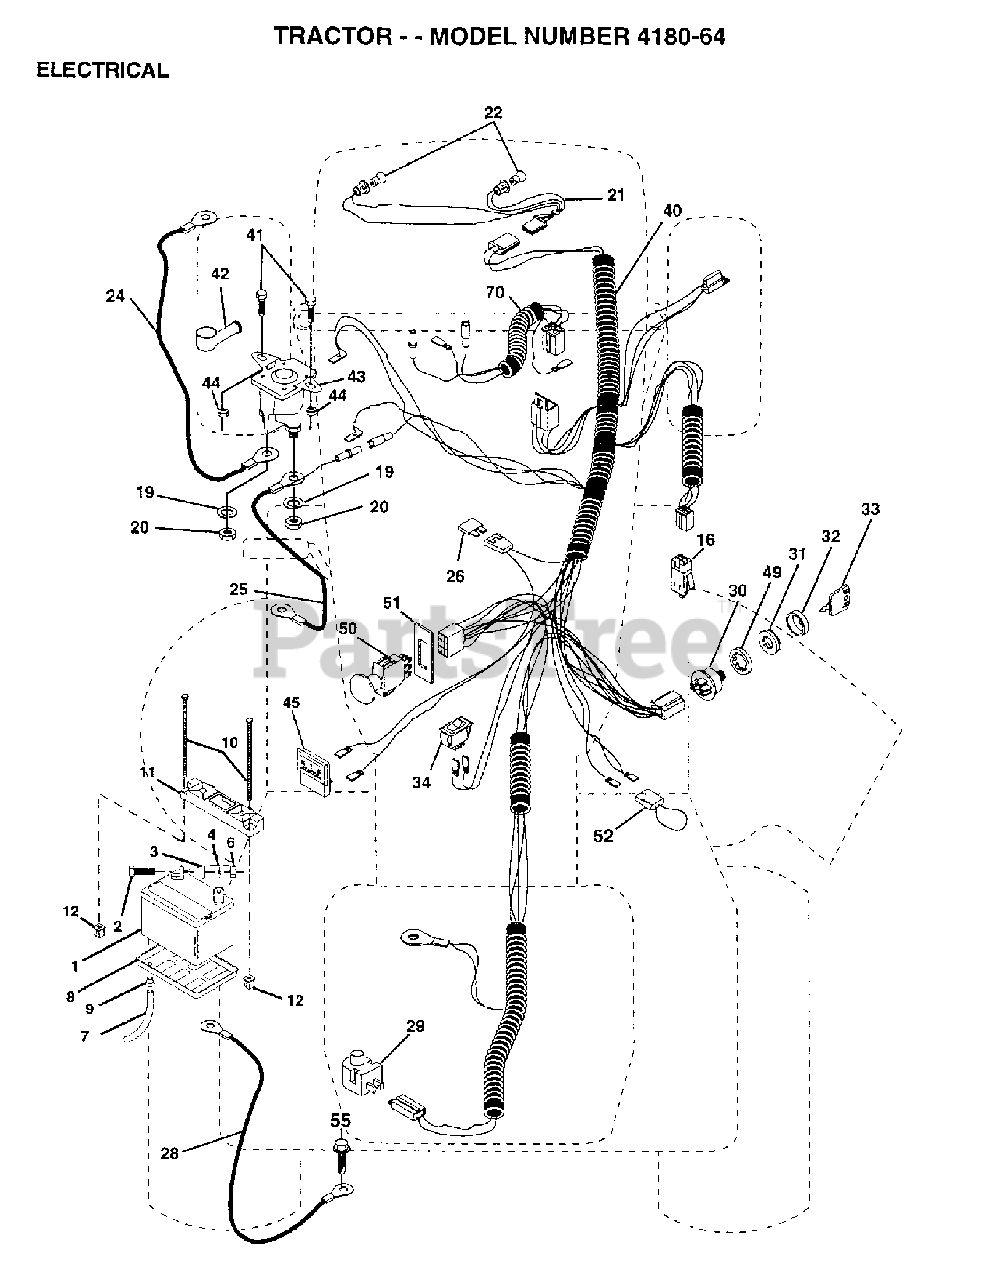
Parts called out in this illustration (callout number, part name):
1	BATTERY 12 VOLT 30 AMP WET
2	BOLT.HEX.1/4.X.3/4.DICHROMATE
3	WASHER
4	LOCKWASHER
5	NUT
7	BATT DRAIN TUBE T
8	TRAY.BATTERY
9	HOSE CLAMP T
10	BOLT 1/4-20 X 7.5
20	NUT
22	LIGHTBULB
24	BATTERY CABLE
25	CABLE BATTERY 6 GA 22" W/16W
26	FUSE *
28	CABLE GROUND 6 GA 21" 90T BLK
29	SWITCH SEAT
30	Ignition Switch Kit
31	NUT, IGNITION
32	COVER KEY IGNITIO
33	KEY MLD GEN DELTA
34	SWITCH LT
41	BOLT
42	TERMINAL COVER
43	Solenoid Kit, .95
44	NUT.HEX.KEPS.1/4-20
49	Poulan TBD
50	SWITCH-PTO
51	RETAINING RING
52	WIRE PROTECTION LOOP
55	SCREW LT
